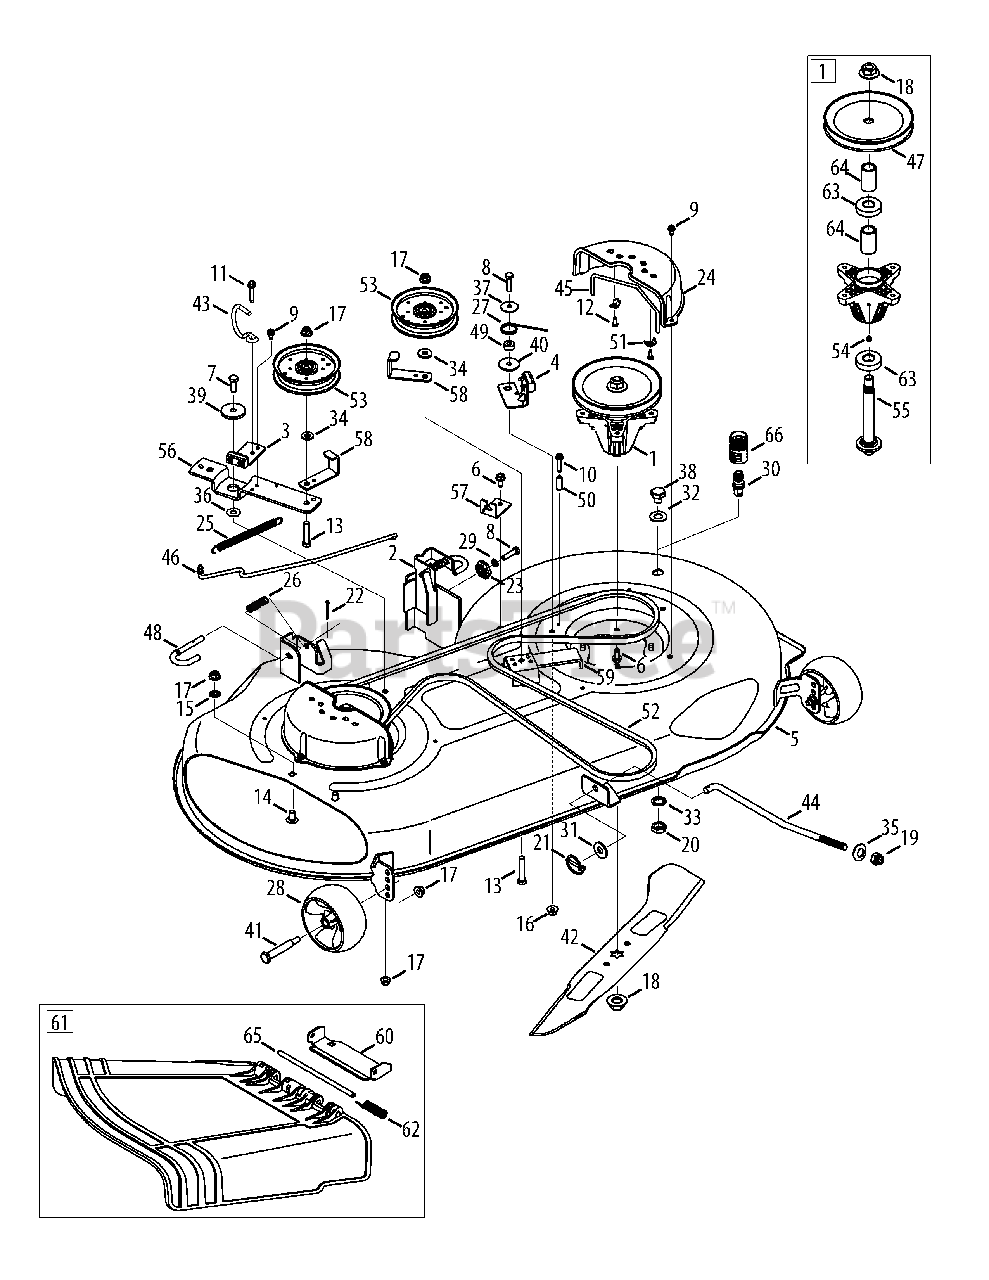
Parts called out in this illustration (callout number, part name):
1	Spindle Ass’y, Pulley, 6.93 Dia
2	Bracket Ass’y, Deck, Hanger LH
3	Brake Ass’y, Deck
4	Brake Ass’y, Deck
5	Deck Ass’y, Offset, 46"
6	Screw, Self-tapping, 5/16-18x.750
7	Hex Screw, 3/8-16x1.00
8	Hex Screw, 5/16-18x1.25
9	Screw, Self-tapping, 1/4-20x0.500
10	Screw, Self-tapping, 1/4-20x1.500
11	Screw, Self-tapping, 1/4-20x.75
12	Screw, #10-16x.625
13	Hex Screw, 3/8-16x2.00
14	Bolt, Carriage, 3/8-16x0.75
15	Nut, Push, 3/8
16	Nut, Flange Lock, 5/16-18
17	Nut, Flange Lock, 3/8-16
18	Nut, Flange, 5/8-18
19	Nut, Lock, 1/2-13
20	Nut, Hex, M16-1.5
21	Pin, Lynch, .1875
22	Pin, Cotter, 1/8 x 1.25
23	Gear, Deck, Adjustment
24	Belt Cover
25	Spring, Extension, .62 Dia x 6.12
26	Spring, Comp, .535 OD x 1.751
27	Spring, Torsion, .992 I.D x 1.17 O.D
28	Wheel, Deck, 5.0 Dia Ball
29	Washer, Lock, 5/16, Regular Duty
30	Water Nozzle Adaptor
31	Washer, Flat, .531 x 1.25 x .100
32	Washer, Flat, .64 x 1.24 x .06
33	Washer, Lock, 5/8, Int Tooth
34	Washer, Flat, .385 x .870 x .092
35	Washer, Bell, .63 x 1.25 x .18
36	Washer, Flat, .385 x 1.0 x .030
37	Washer, Flat, .330 x 1.25 x .06,
38	Plug, Bolt, M16 x 1.5
39	Spacer, Shoulder, .8840 x .190
40	Spacer, Shoulder
41	Bolt, Shoulder, .496 x 2.50, 3/8-16
42	Blade
43	Rod, Keeper, Belt
44	Rod, Lift, Deck, Frt
45	Rod, Keeper, Belt
46	Rod, Control, Brake
47	Pulley, Deck, 6.93 Dia
48	Rod, Handle, Deck Release
49	Spacer, .315 x .750 x .375
50	Spacer, .260 x .375 x 1.030
51	Clamp, Casing
52	Belt, V-Type
53	Pulley, Idler, 4.25"Dia
54	Fitting, 3/16, Drive Lube
55	Shift, Spindle, 6.11.
56	Bracket, Idler, Pivot
57	Bracket, Cable, Deck Engage
58	Bracket, Guard, Belt
59	Bracket, Support, Deck Stationary Idler
60	Bracket, Chute
61	Chute Ass’y, Deflector
62	Torsion Spring, .44 ID x 2.0
63	Ball Bearing, .787 ID x 1.85 OD x .551
64	Spacer, .792 x 1.060 x 1.860
65	Hinge Pin
66	Deck Water Nozzle
